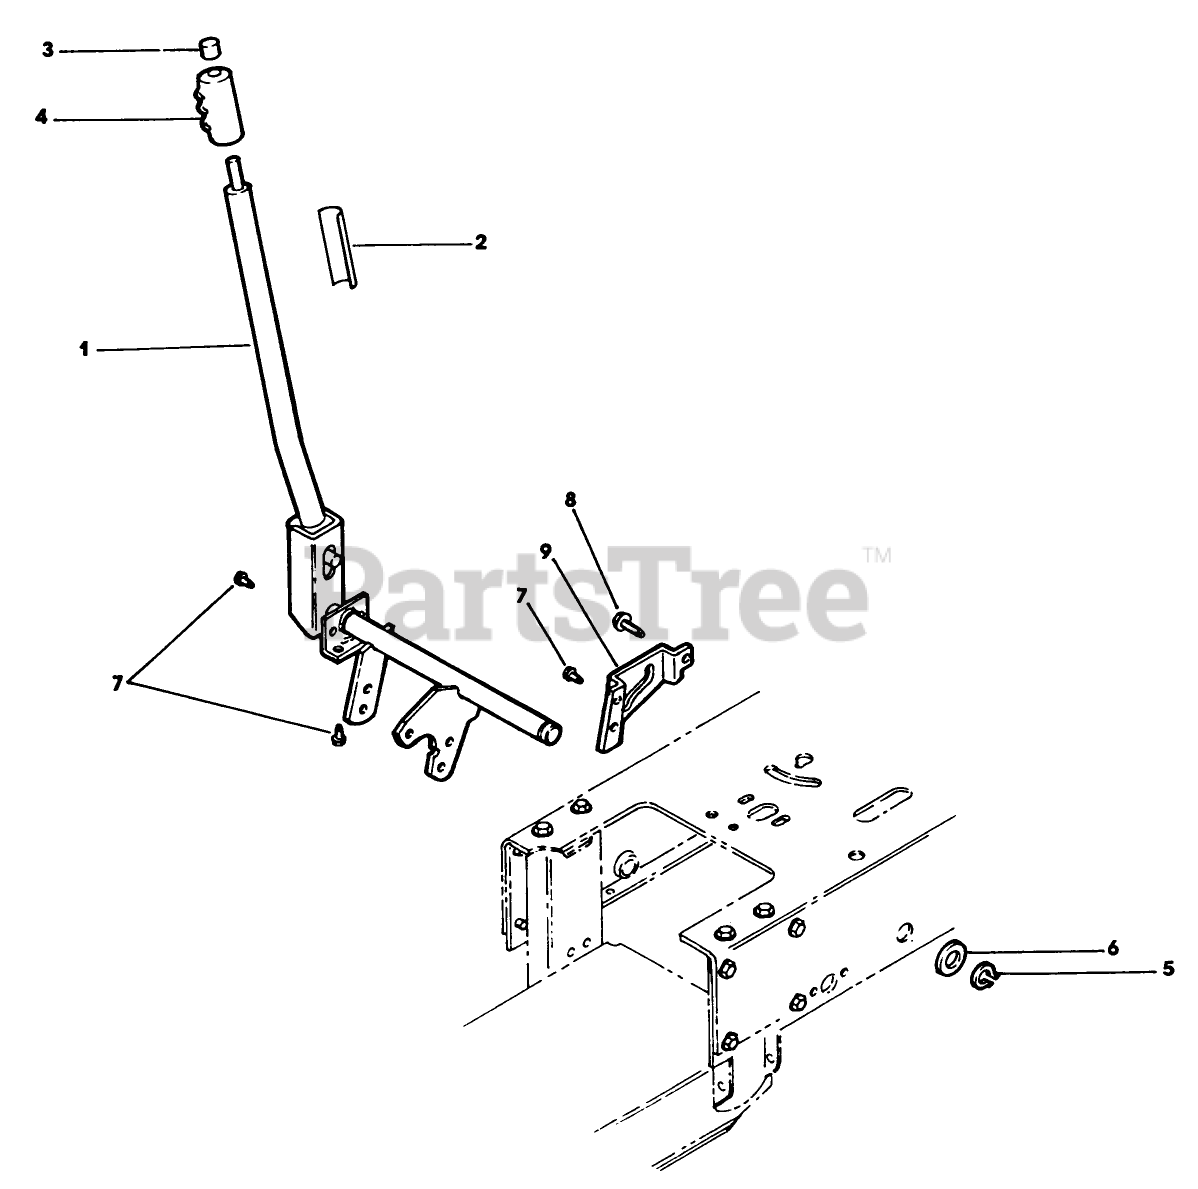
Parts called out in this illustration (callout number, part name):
2	STICKER-LIFT
3	TIP-ROD
5	RING-RETAINING
6	WASHER
